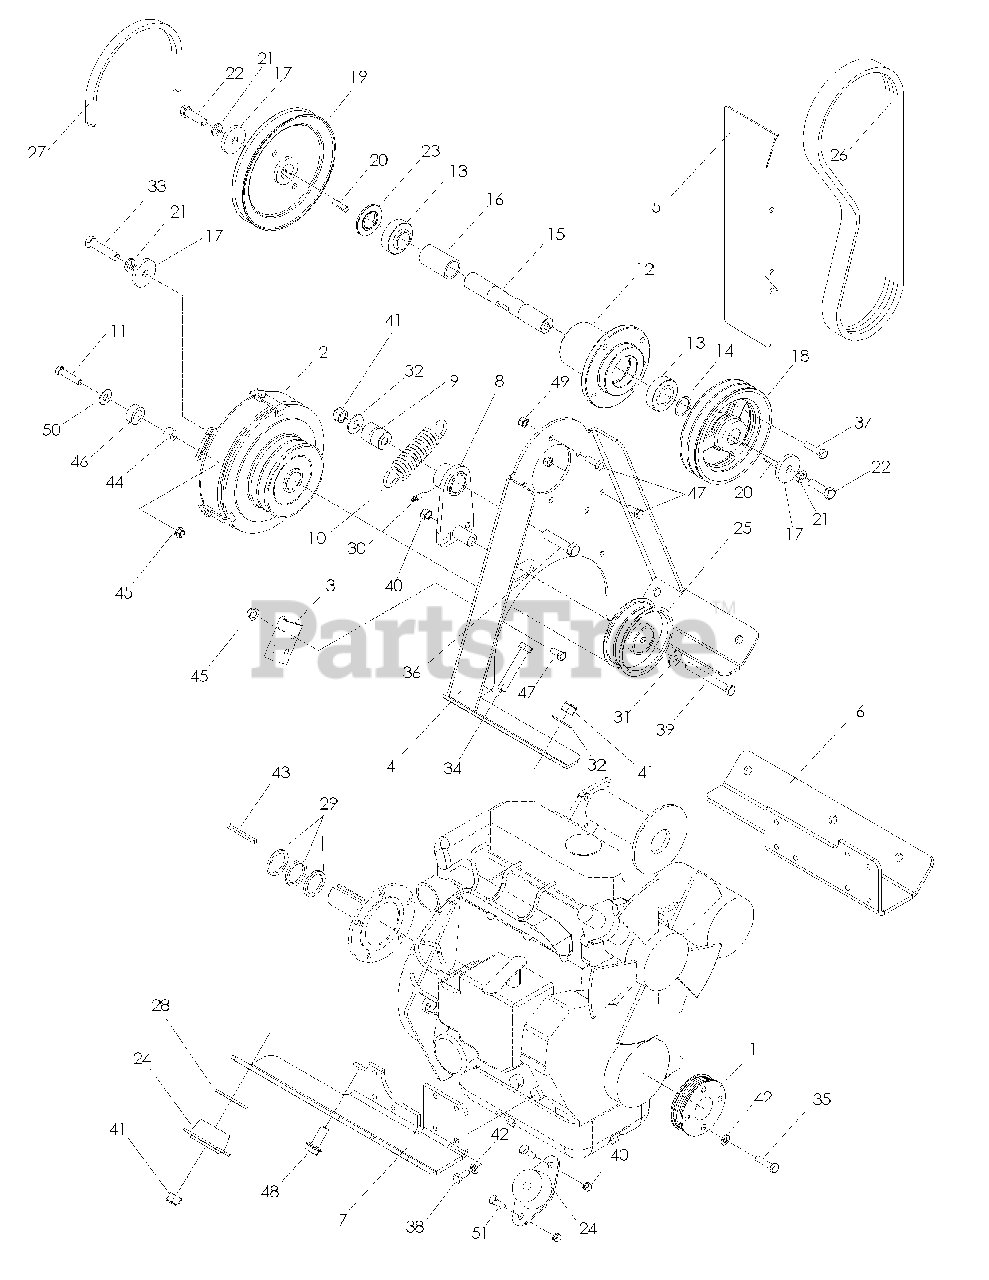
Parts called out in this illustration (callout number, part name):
1	SHEAVE, ENGINE
4	JACK MOUNT WLDMT
5	HEAT SHIELD
6	ENGINE MOUNT LT
7	ENGINE MOUNT RT
11	HCS 5/16-18 x 1 1/4
14	MACHINE BUSHING, 18 GA
17	WASHER, HEAVY
20	KEY 1/4 SQ x 1 1/8
21	WASHER 7/16 SPLT LOCK
22	HCS 7/16-20 x 1 1/2
23	COMBO SPACER
24	ISO MOUNT
26	BELT, PRIMARY
27	BELT, MULE
28	WASHER, HEAVY
29	MACHINE BUSHING, 1 1/8 x 10
30	ZERK, LONG
31	WASHER 3/8 SAE FLT
32	WASHER 1/2 FLAT
33	HCS 7/16 x 2 1/2
34	HCS 1/2-13 x 2 3/4
35	BOLT M8-1.25 x 35mm
36	HCS 1/2-13 x2 1/2
37	HCS 5/16-18 x 1
38	HCS M8-1.25 x 20mm
39	HCS 3/8-16 x 3 1/2
40	NUT 3/8-16 HEX NYLOC
41	NUT 1/2-13 HEX NYLOC
42	WASHER 5/16 SLOTTED LOCK
43	KEY 1/4 SQ x 2 1/2
45	NUT 5/16-18 WHIZ
47	HCS 5/16-18 x 3/4
48	BOLT 1/2-13 x 1 1/4 WHIZLK
49	NUT 5/16-18 HEX NYLOC
50	WASHER 5/16 STD FLT
51	HCS 3/8-16 x 1
